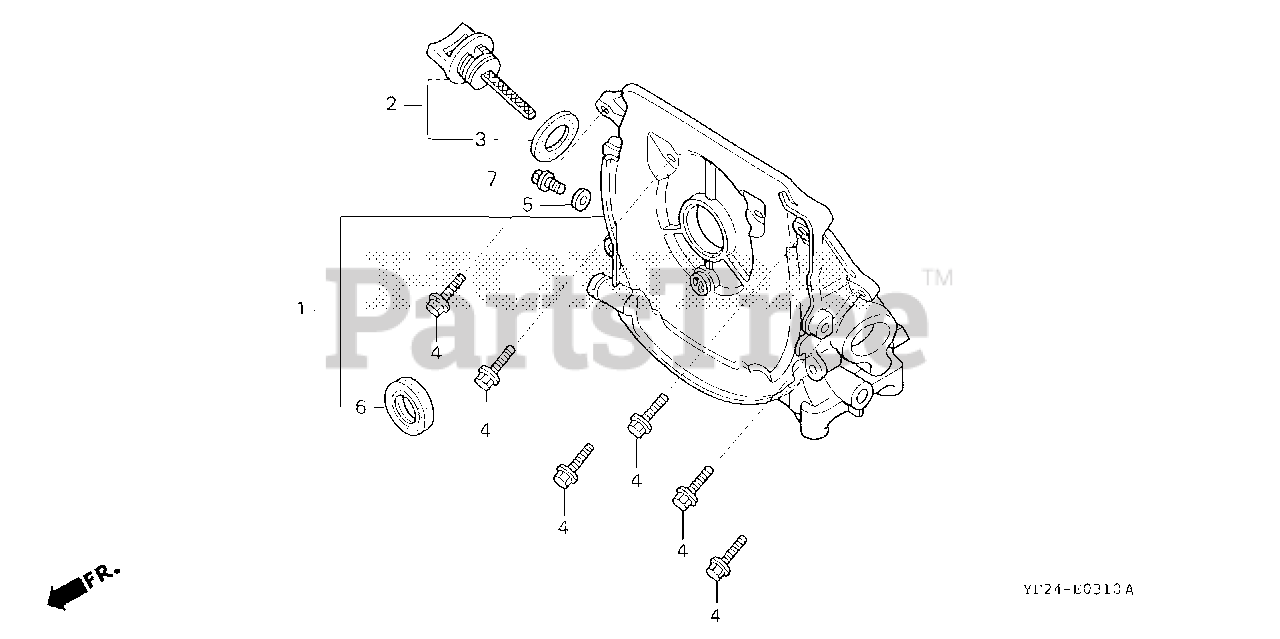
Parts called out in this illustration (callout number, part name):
1	CASE ASSY., OIL
2	CAP ASSY., OIL FILLER
3	GASKET, OIL FILLER CAP
4	BOLT, FLANGE (5X23)
5	GASKET (8MM)
6	OIL SEAL (17X27X5) (KOYO)
7	BOLT, FLANGE (8X12)
